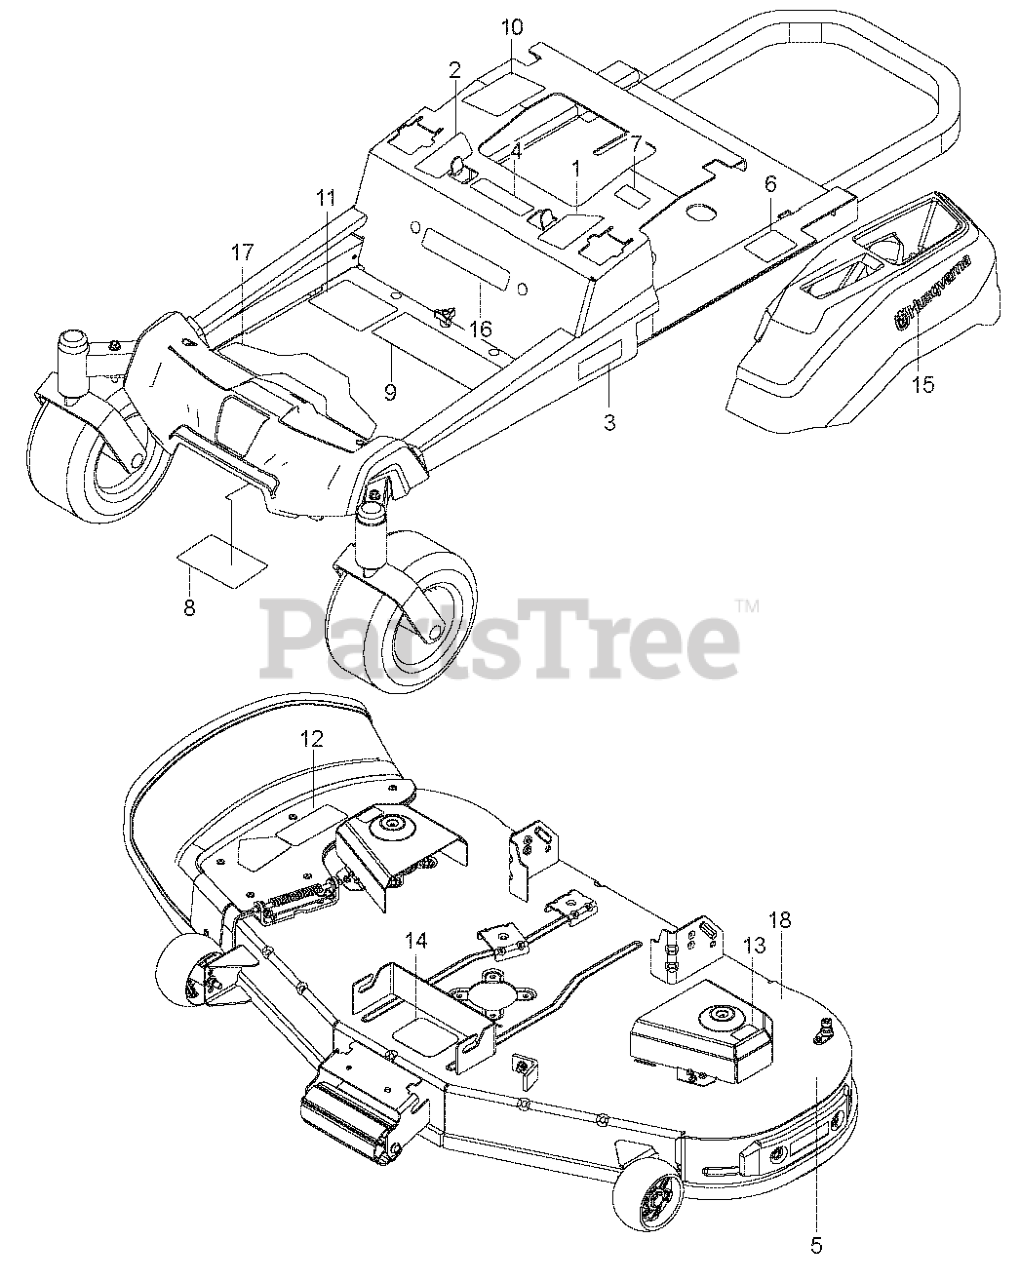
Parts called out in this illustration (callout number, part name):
1	DECAL.ZTR.RZ.THRTL/PRKBRK.V2.L
2	DECAL.ZTR.RZ.THRTL/PRKBRK.V2.R
3	DECAL.ZTR.SIDERAIL.MN.Z248F.HU
4	EURO DECAL-BATTERY WARNIN6
5	DECAL DECK DECAL DECAL.48DECK.
6	DECAL, DO NOT TOW
7	DECAL, EXITING MOWER
8	DECAL, SERVICE
9	DECAL ZTR WARNING DECAL DECAL.
10	DECAL.WARNING.CUST.RESP.E85.
11	DECAL.ZTR.STARTINSTRCT.CHOKE15
12	DECAL.TRACT/ZTR.DECKWARN.HUSQ
13	DECAL.DECK.CLEARCUT.NOSTEP
14	DECAL, BELT ROUTING
15	DECAL.HUSQVARNA.210MM
16	DECAL ZTR BRAND GRAPHIC DECAL.
17	PAD.RZ.FOOTREST.PLATE
18	DECAL DECK DECAL DECAL.DECK.WA
